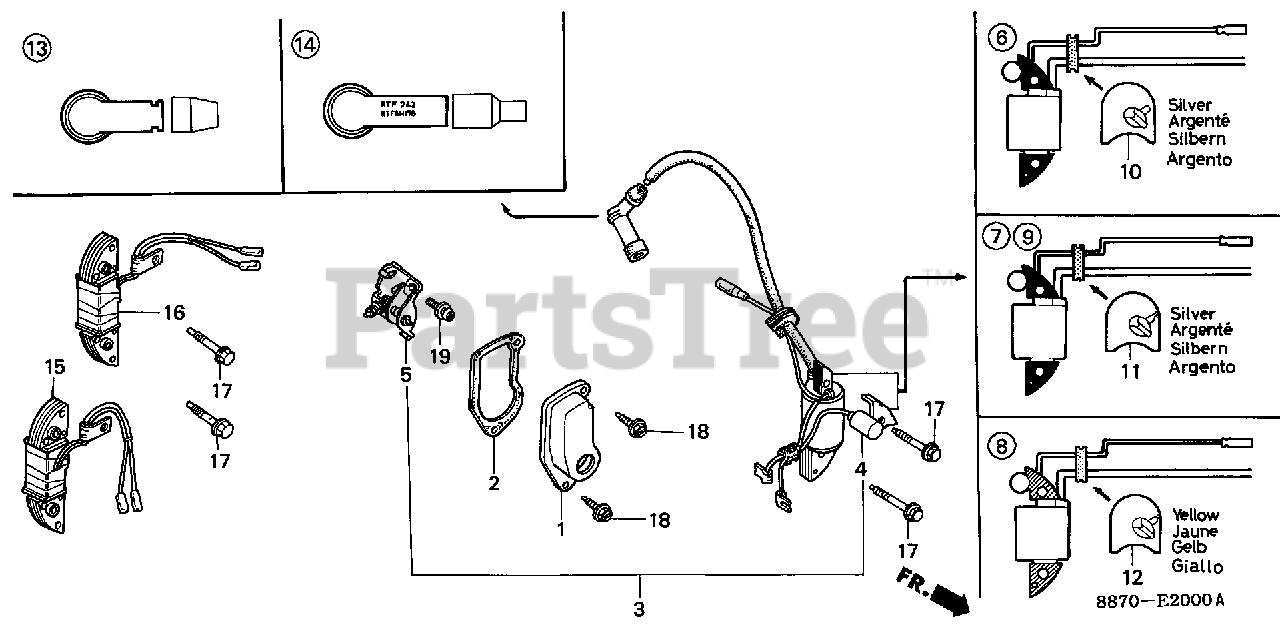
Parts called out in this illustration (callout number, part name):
1	COVER, BREAKER
2	GASKET, POINT COVER
4	CONDENSER
5	POINTS ASSY.
6	COIL ASSY., IGNITION
10	GROMMET, WIRE
14	CAP ASSY., NOISE SUPPRESSOR
17	BOLT, FLANGE (6X32)
18	BOLT, FLANGE (5X10)
19	SCREW-WASHER (5X12)
